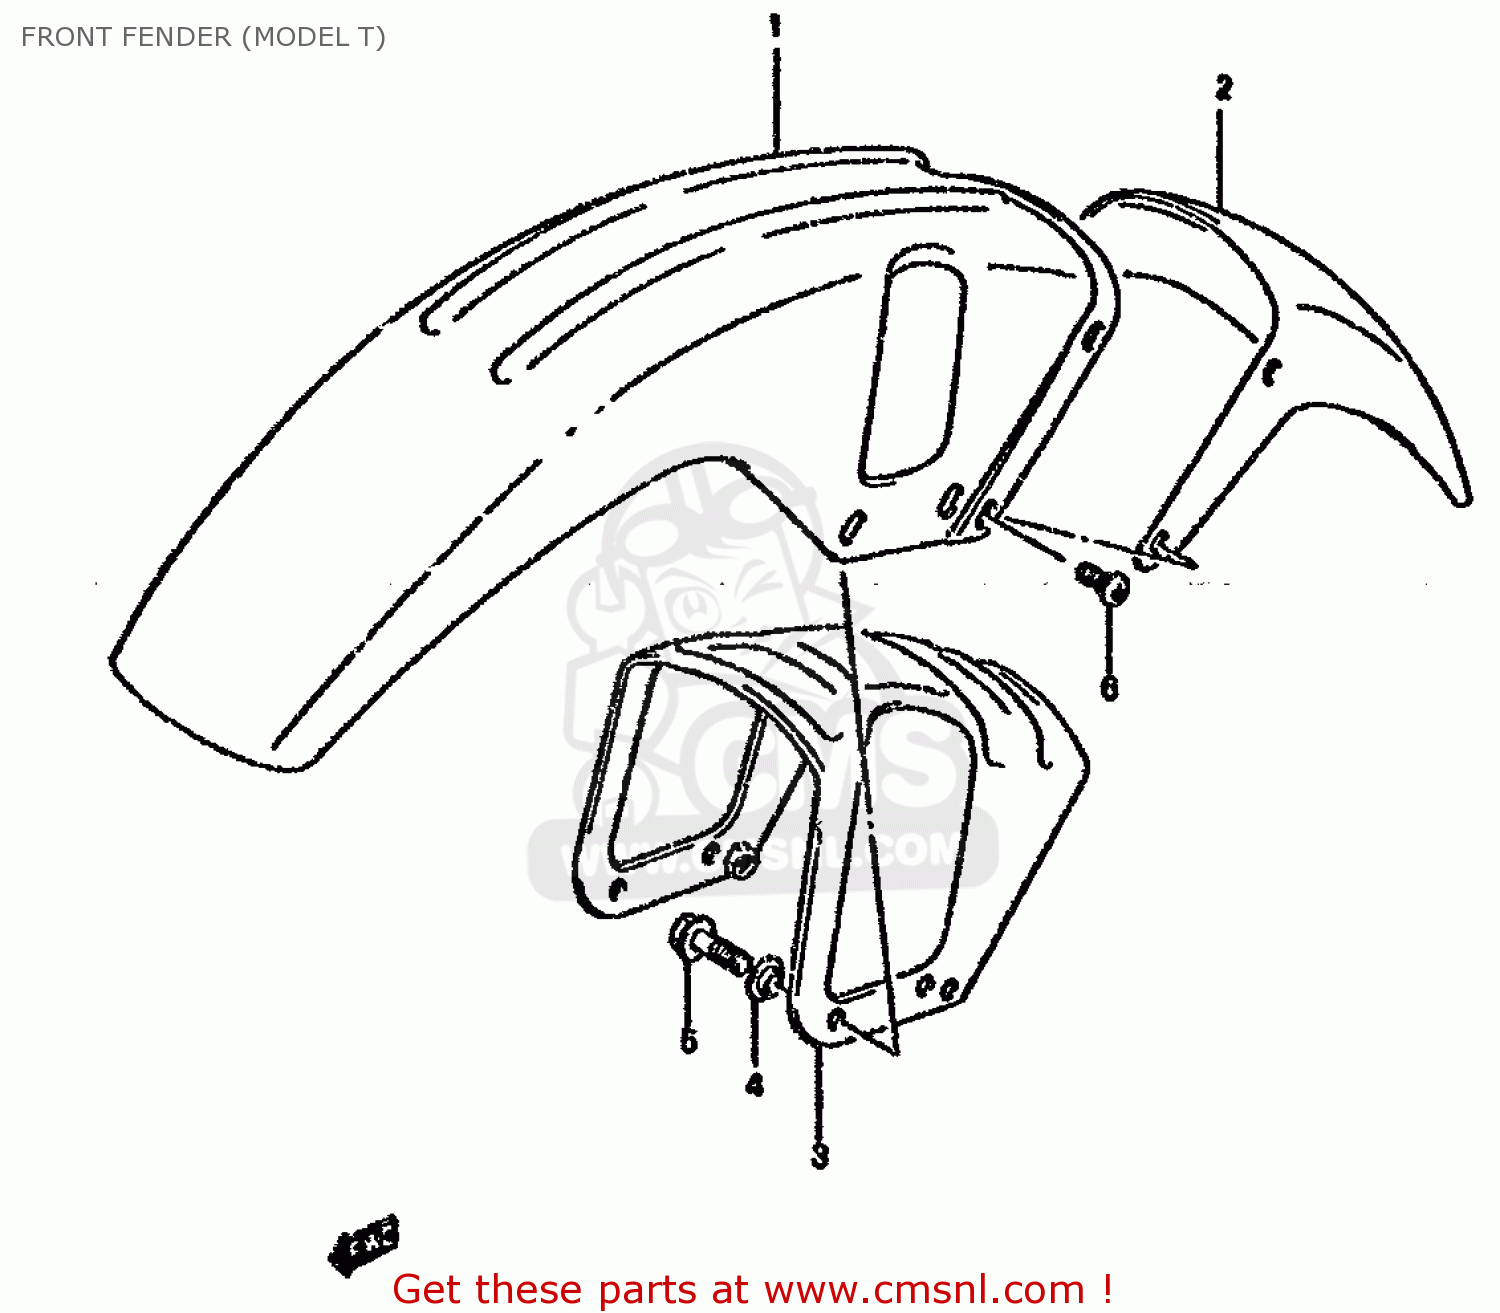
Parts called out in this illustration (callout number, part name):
1	FENDER,FR NO,1
2	FENDER,FR NO,2
3	FENDER,FR NO,1
4	WASHER
5	BOLT
6	WASHER
7	BOLT
8	SCREW 5X12
